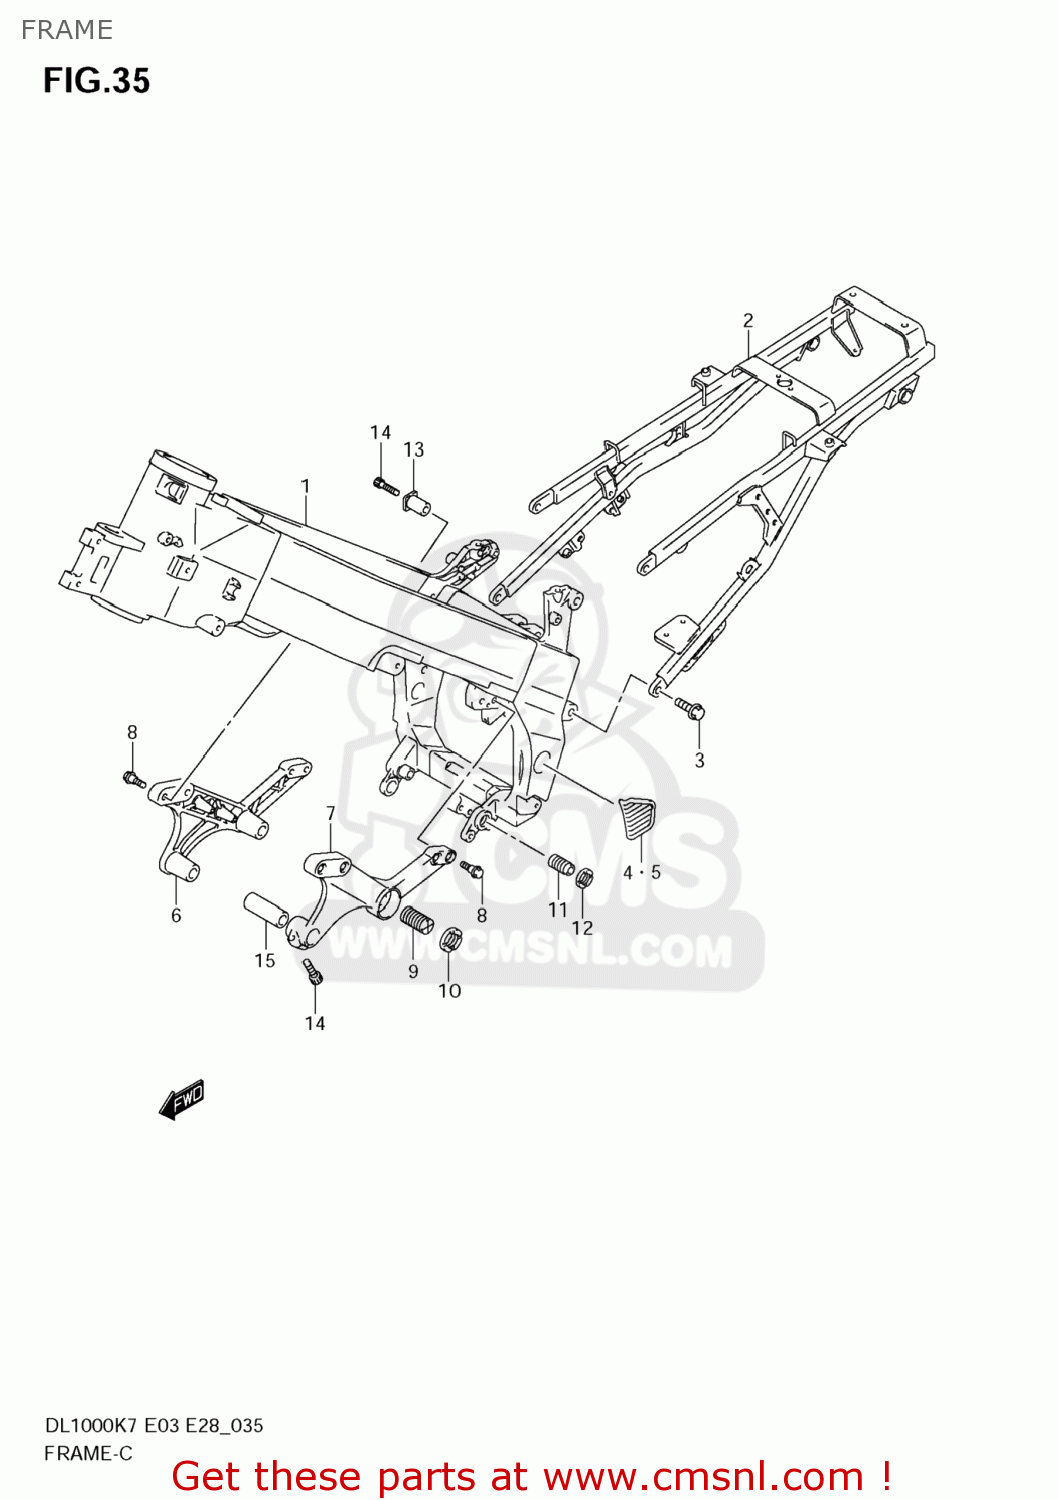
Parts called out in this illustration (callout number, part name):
1	FRAME(BLACK)
2	RAIL,SEAT
3	BOLT(10X30)
4	COVER,PIVOT,R
5	COVER,PIVOT,L
6	BRACKET,ENGINE MOUNTING,R
7	BRACKET,ENGINE MOUNTING,L
8	BOLT(8X30)
9	BOLT,CRANK CASE ADJUST CTR
10	NUT,CRANKCASE ADJUST
11	BOLT,CASE LWR & RR HEAD ADJ
12	NUT,CRANK CASE ADJUST BOLT
13	SPACER,MOUNTING RR UPR,R
14	BOLT
15	SPACER,ENG HEAD MTG FR,L
